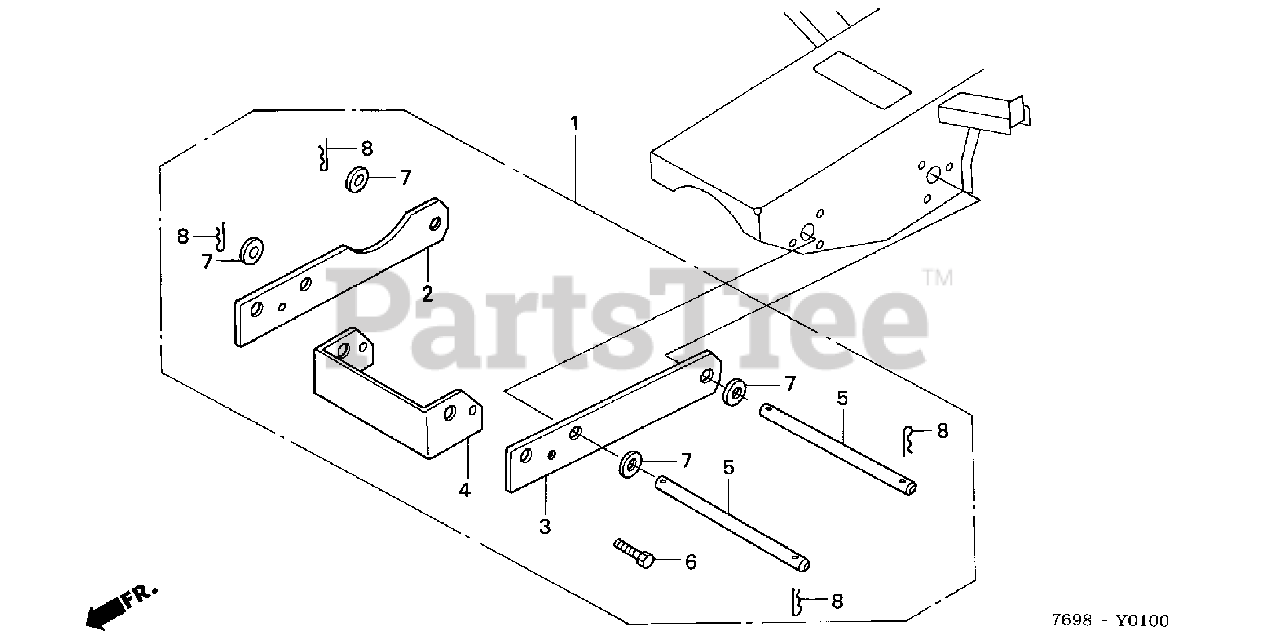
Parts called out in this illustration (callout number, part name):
1	ADAPTER KIT, COUNTERWEIGHT (NOT AVAILABLE)
2	BRACKET, R. FR. END ADAPTER
3	BRACKET, L. FR. END ADAPTER
4	BRACKET, FR. SUPPORT
6	BOLT, HEX. (12X40)
7	WASHER, FLAT (7/8")
8	HAIRPIN (4X80)
